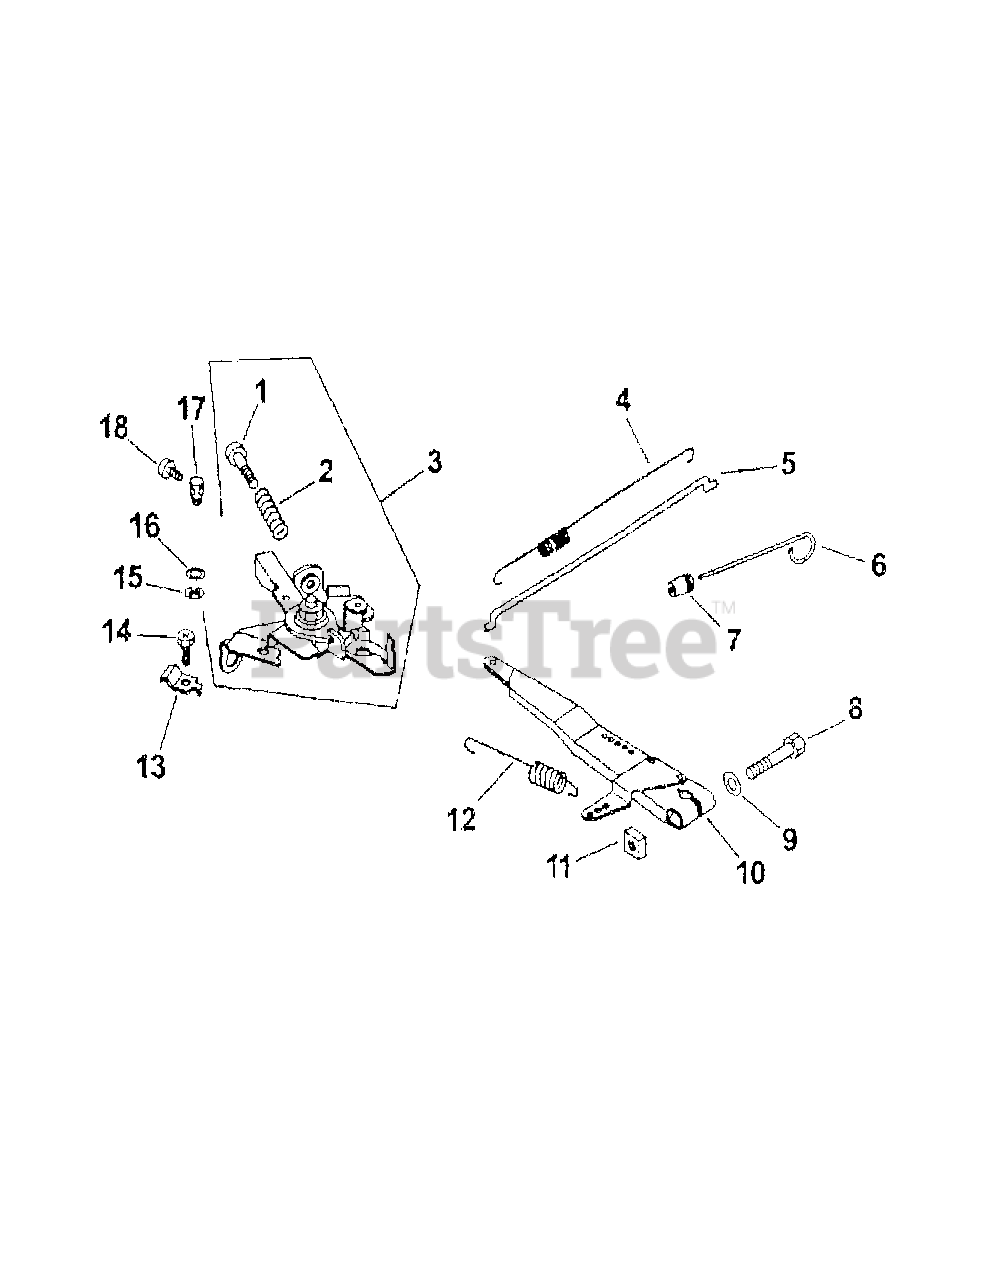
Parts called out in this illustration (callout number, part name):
1	Screw, Throttle Plate
2	Spring, Compression
3	Throttle Lever
4	Spring, Linkage
5	Link, Throttle
7	Grommet
10	Lever, Governor
12	Spring, Governor
13	Clamp, Bowden
14	Screw, Bowden Clamp
17	Clamp, Wire
